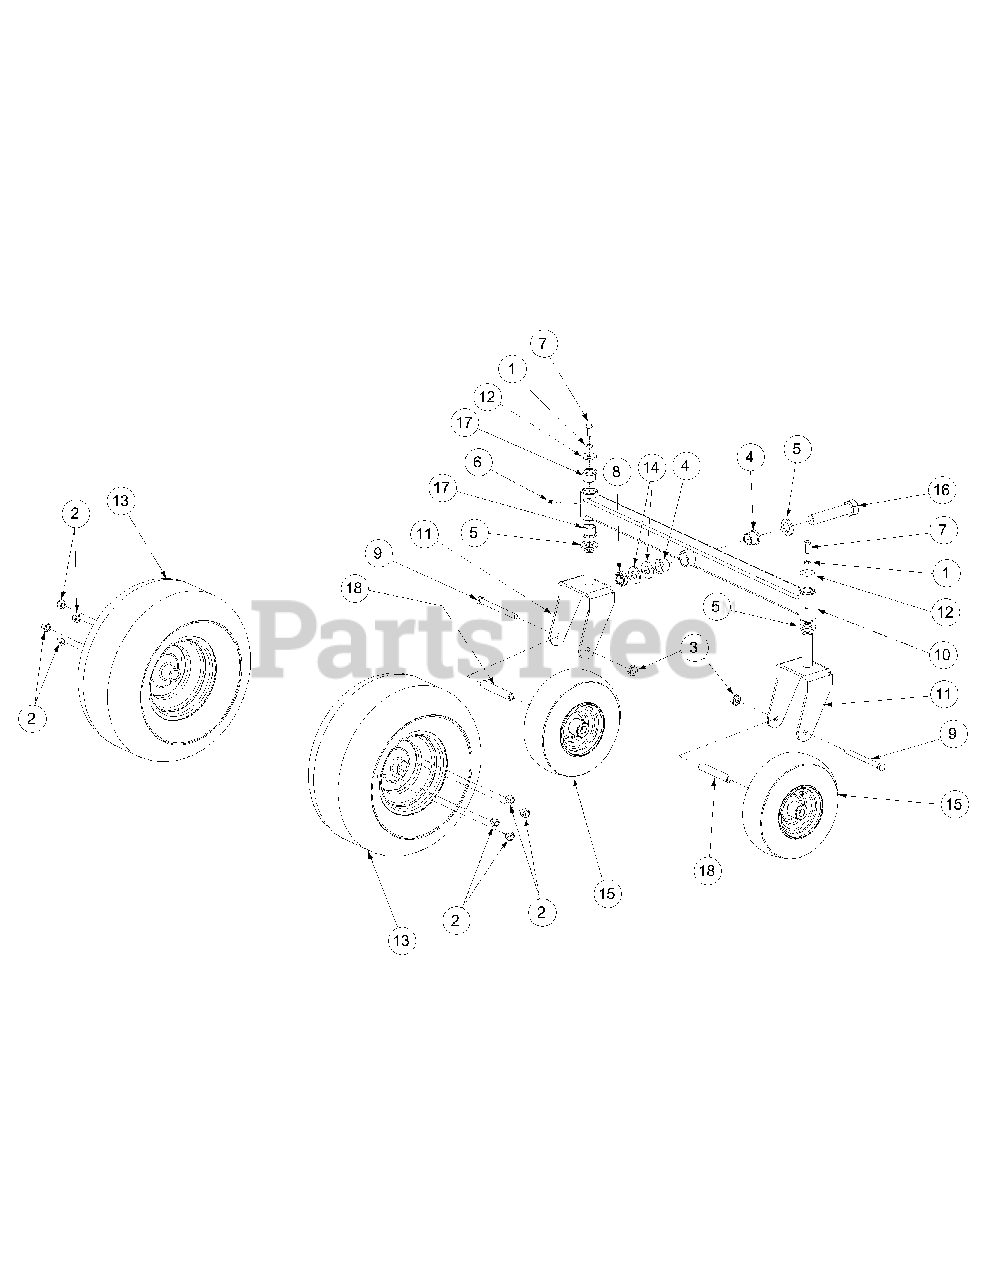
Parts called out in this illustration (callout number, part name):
1	Lock Washer, 3/8 Zinc
2	Lug Nut, 1/2-20
3	Nut, 1/2-20, Center Lock
4	Flange Bearing, 1.013 ID
5	Washer Special
6	Grease Fitting, 1/4-28 x 3/16
7	Hex Cap Screw, 3/8-16 x .88
8	Nut Jam, 1.0-14, Nylon Insert
9	Hex Cap Screw, 1/2-20 x 5.50
10	Front Axle Assembly
11	Castor Wheel Mounting Bracket
12	Flat Washer, .390 x 1.5 x .134
13	Wheel Assembly, 18 x 9.5
14	Flat Washer, 1.00 ID x 2.25 OD x ,075
15	Wheel Assembly, 11 x 4 - 4, Beige
16	Hex Cap Screw, 1-14 x 5.5
17	Flange Bearing, 1.0 ID
18	Wheel Spacer
